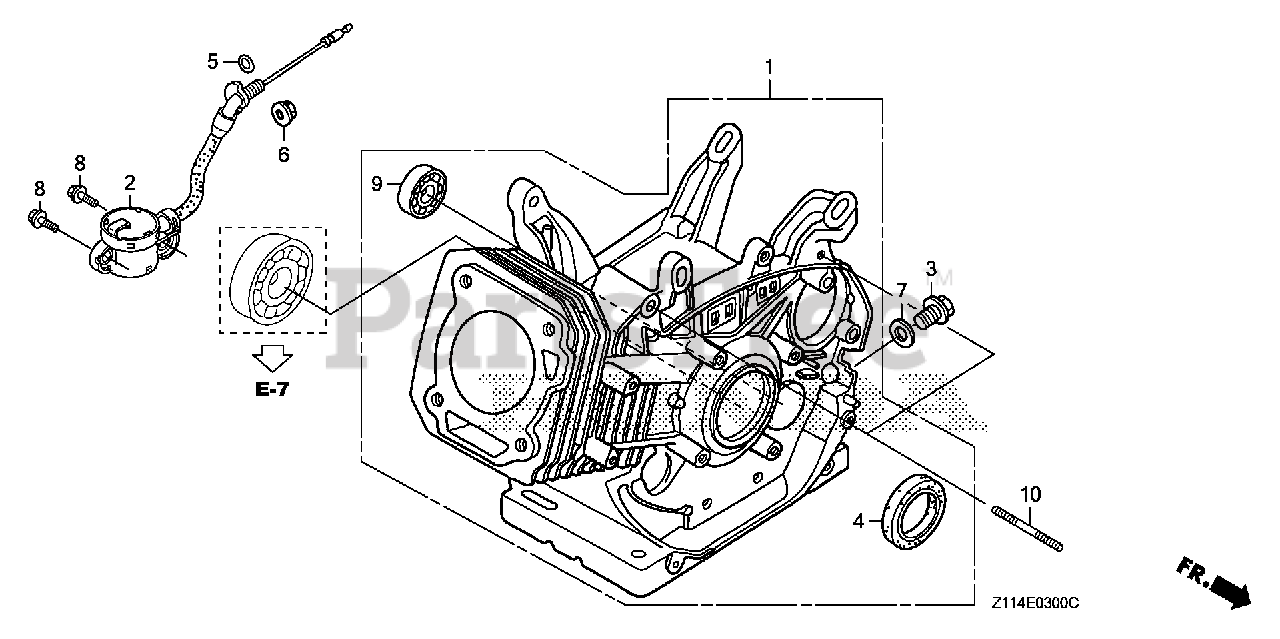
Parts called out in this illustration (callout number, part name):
1	CYLINDER ASSY.
2	SWITCH ASSY., OIL LEVEL
3	BOLT, DRAIN PLUG (12X15)
4	OIL SEAL (35X52X8)
5	O-RING (13.5X1.5) (ARAI)
5	O-RING (14MM) (NOK)
6	NUT, FLANGE (10MM)
7	WASHER, DRAIN PLUG (12MM)
8	BOLT, FLANGE (6X12)
9	BEARING, RADIAL BALL (6202)
10	BOLT, STUD (6X30)
